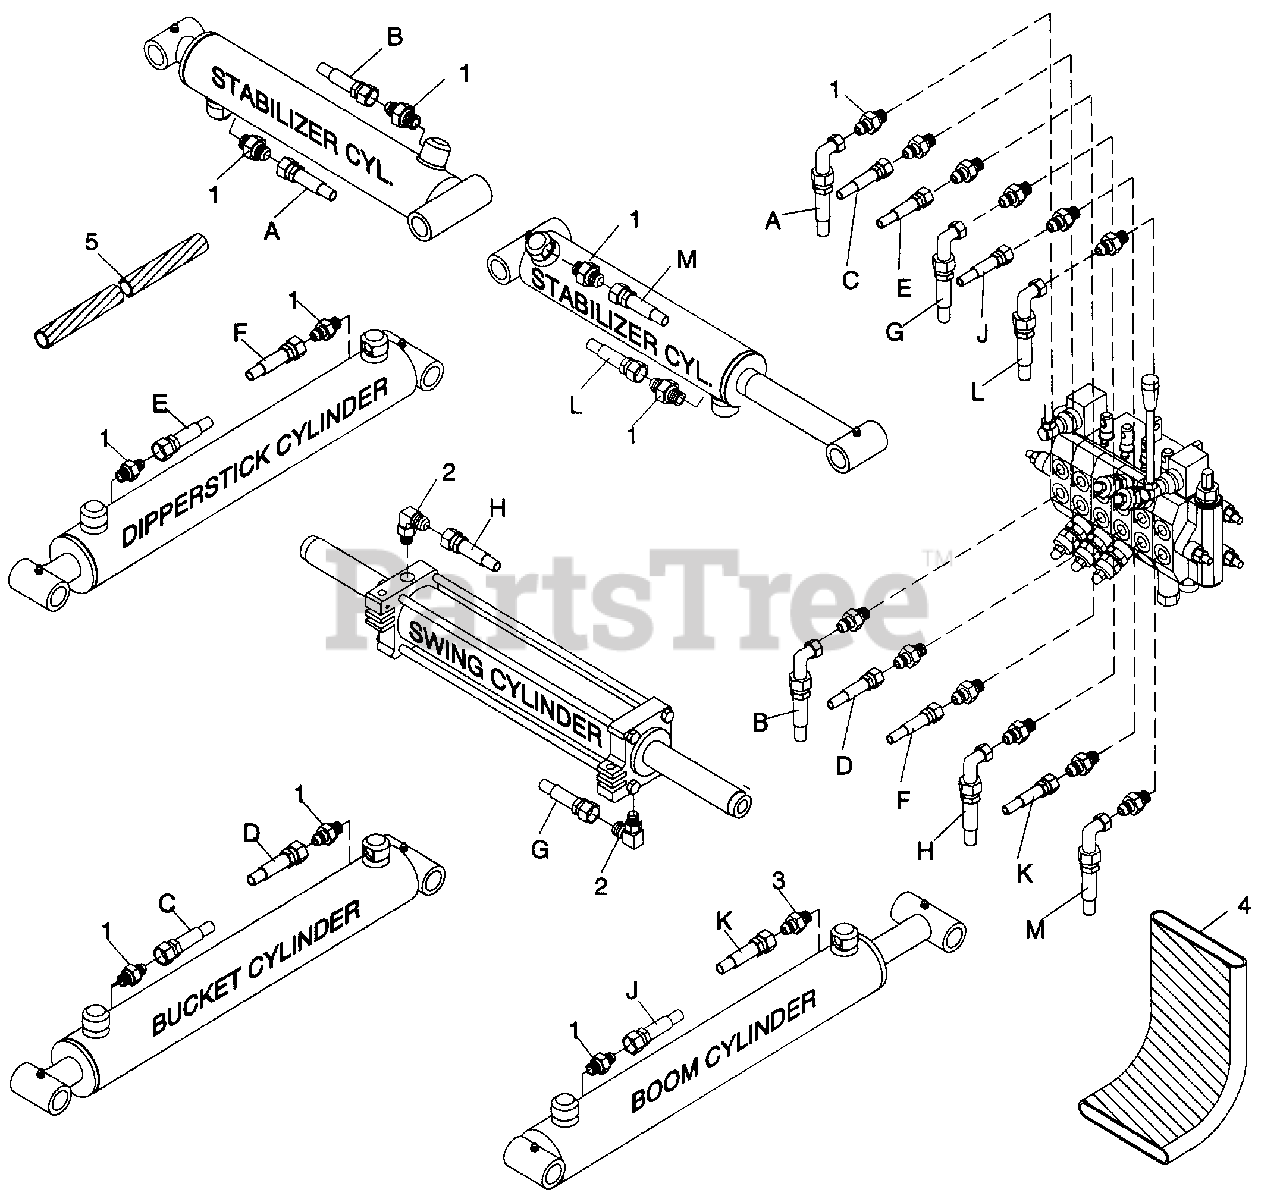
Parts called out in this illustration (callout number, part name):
1	9/16 - 18 To O-Ring connector
2	9/16 x 9/16 Swivel elbow
3	9/16 JIC M x 9/16 SAE M Adapter with 3/32 restrictor
4	4" DIA x 34" Sleeve
5	1" DIA x 15" Sleeve
A	Hose-1/4 x 9/16 JICF x 9/16 JICF x 45
B	Hose-1/4 x 9/16 JICF x 9/16 JICF x 45
C	Hose-5/16 x 9/16 JICF x 9/16 JICF x 107
D	Hose-5/16 x 9/16 JICF x 9/16 JICF x 107
E	Hose-5/16 x 9/16 JICF x 9/16 JICF x 82
F	Hose-5/16 x 9/16 JICF x 9/16 JICF x 82
G	Hose-1/4 x 9/16 JICF x 9/16 JICF x 45
H	Hose-1/4 x 9/16 JICF x 9/16 JICF x 45
J	Hose-5/16 x 9/16 JICF x 9/16 JICF x 82
K	Hose-5/16 x 9/16 JICF x 9/16 JICF x 82
L	Hose-1/4 x 9/16 JICF x 9/16 JICF x 45
M	Hose-1/4 x 9/16 JICF x 9/16 JICF x 45
